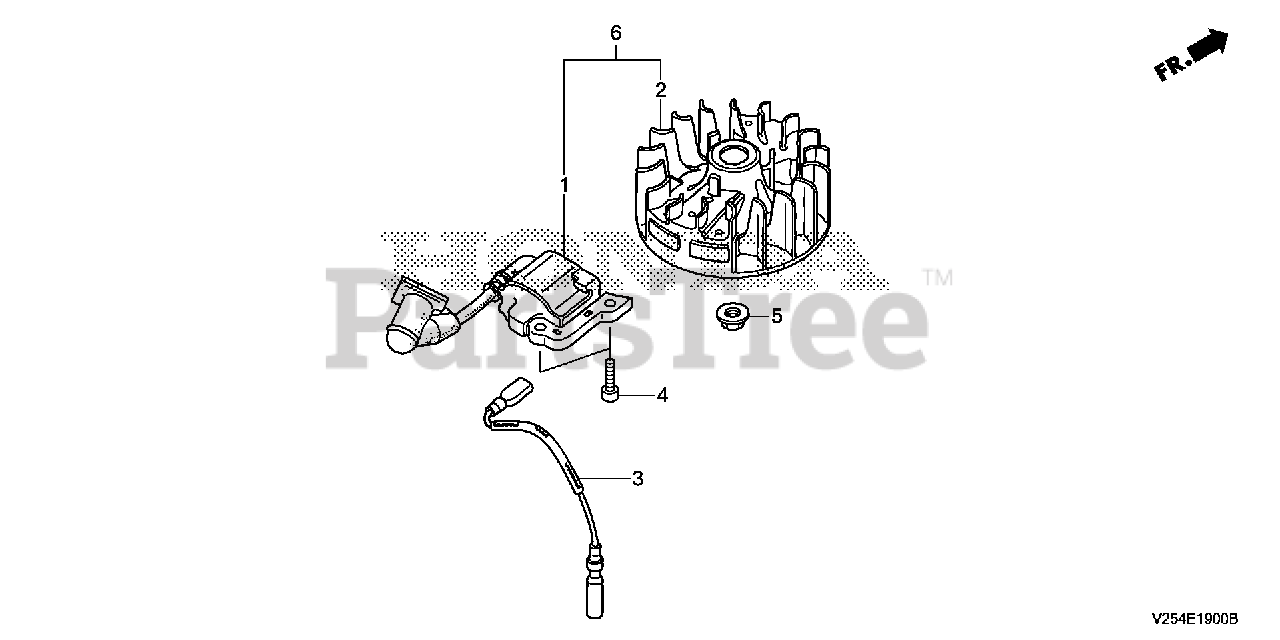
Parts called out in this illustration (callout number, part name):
1	COIL ASSY., IGNITION
3	WIRE, STOP SWITCH
4	BOLT, SOCKET (4X14)
5	NUT, FLANGE (7MM)
